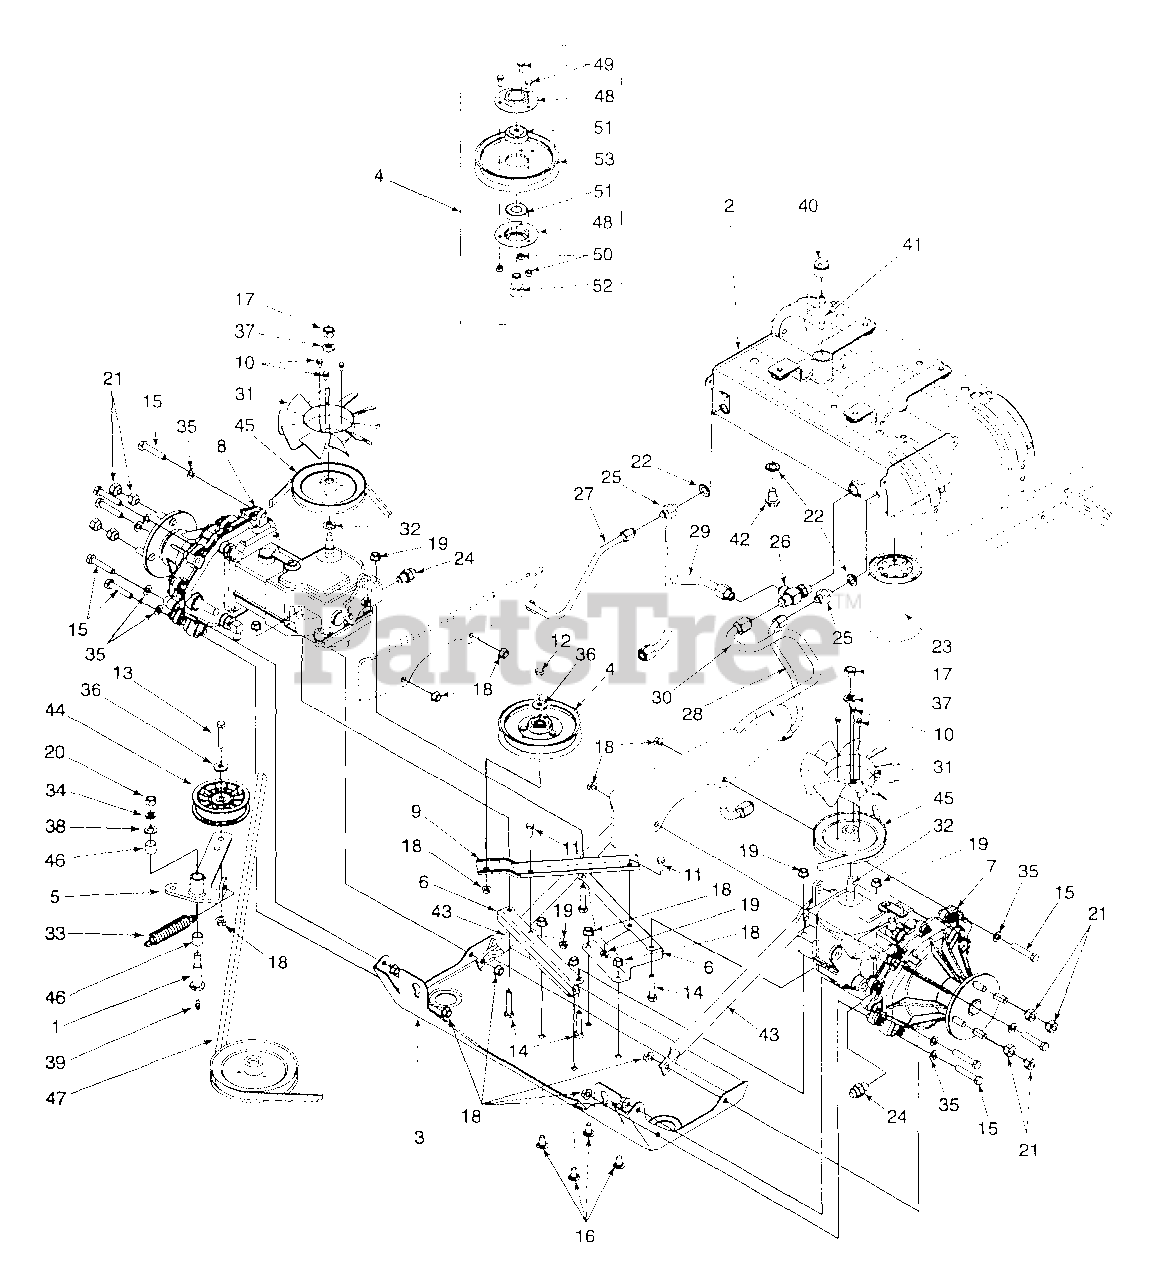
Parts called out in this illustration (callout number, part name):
1	Shoulder Bolt
3	Plate Ass'y, Skid
4	Pulley Ass'y, Idler 5.0 in.
8	Transmission Ass'y LH
11	Screw, Hex Cap .5/16-18 x .75 GR5
12	Screw, Hex Cap 3/8-16 x 2-1/4 GR5
13	Screw, Hex Cap 3/8-16 x 1-3/4 GR5
14	Screw, Hex Cap 5/16-18 x 2.0 GR5
15	Screw, Hex Cap 3/8-16 x 2.0 GR5
16	Bolt, Carriage, 3/8-16 x .75
17	Nut, Hex, 1/2-20
18	Nut, Hex Flange Lock, 3/8-16
19	Nut, Hex Flange Lock, 5/16-18 GR5
20	Nut, Hex, 7/16-14
21	Nut, Lug, 7/16-14
22	Seal, Drain Plug
23	Filter Element, Oil
24	Fitting, Connector, 1/2 x 3/8
25	Fitting, Connector
26	Fitting, Tee, 1/2 x 1/2 x 3/4
27	Tube, Inlet LH
28	Tube, Inlet RH
29	Tube, Outlet LH
30	Tube, Outlet RH
31	Fan, 10 Blade
33	Spring, Extension
34	Washer, Lock, 7/16
35	Washer, Flat, .406 x .75 x .06
36	Washer, Flat, .385 x 1.0 x .135
37	Washer, Lock, 1/2
38	Washer, Flat, .469 x .875 x .105
39	Fitting, Grease
40	Plug, Pipe, w/Vent 3/4 NPTF
41	Tube, Dipstick
42	Plug, Oil Drain
45	Pulley, Transmission
46	Bearing, Sleeve, .628 x .75 x .625
47	V-Belt, Transmission Drive A-Section x 54.24 Lg
48	Cup, Bearing
49	Screw, Hex Cap, 1/4-20 x .62 GR5
50	Nut, Hex Insert Lock, 1/4-20
51	Bearing, Ball
52	Spacer, Idler
53	Pulley, Idler 5.0 in.
